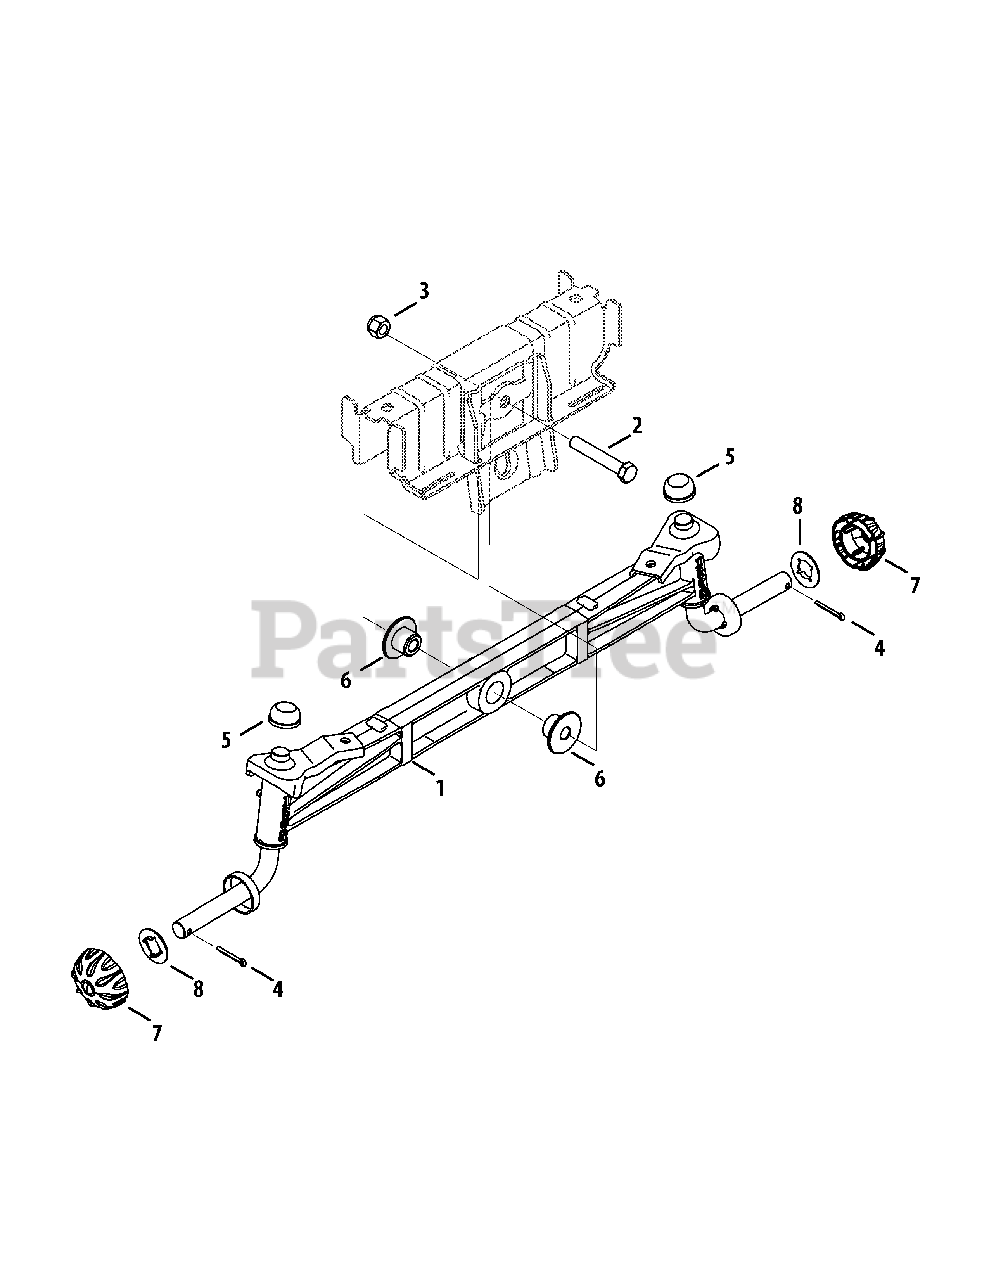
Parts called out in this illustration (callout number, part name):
1	Front Axle Assembly
2	Hex Cap Screw, 1/2-13 x 3.00
3	Nut, Hex Lock, 1/2-13
4	Pin, Cotter, 5/32, 1.25
5	Push Cap, 3/4
6	Shoulder Spacer, 1.00 x .515 x .760
7	Hub Cap
8	Washer, Flat, .350 x 1.559 x .062
